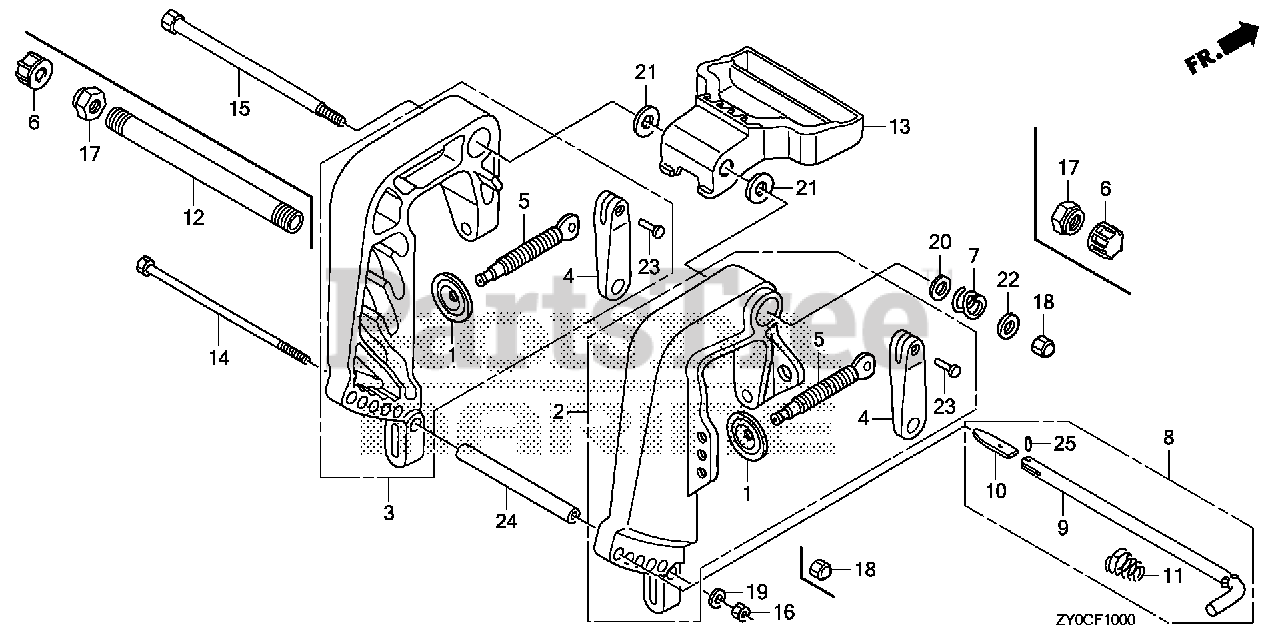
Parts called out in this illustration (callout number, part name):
1	PLATE, PUSH
2	BRACKET, R. STERN *NHB14M* (AQUA MARINE SILVER METALLIC)
3	BRACKET, L. STERN *NHB14M* (AQUA MARINE SILVER METALLIC)
4	GRIP, CLAMP
5	SCREW, CLAMP
7	SPRING, TILT
8	ROD, ADJUSTING
9	ROD, ADJUSTING
10	STOPPER, ROD
11	SPRING, ADJUSTING ROD
13	HANDLE, CARRYING
14	BOLT, HEX. (6X160)
15	BOLT, TILTING
16	NUT, HEX. (6MM)
18	NUT, SELF-LOCK (8MM)
19	WASHER, PLAIN (6MM)
20	WASHER, PLAIN (10MM)
21	WASHER (10MM)
22	WASHER (8MM)
23	RIVET (4X22.6)
24	COLLAR, DISTANCE (6MM)
25	PIN, SPRING (2X8)
